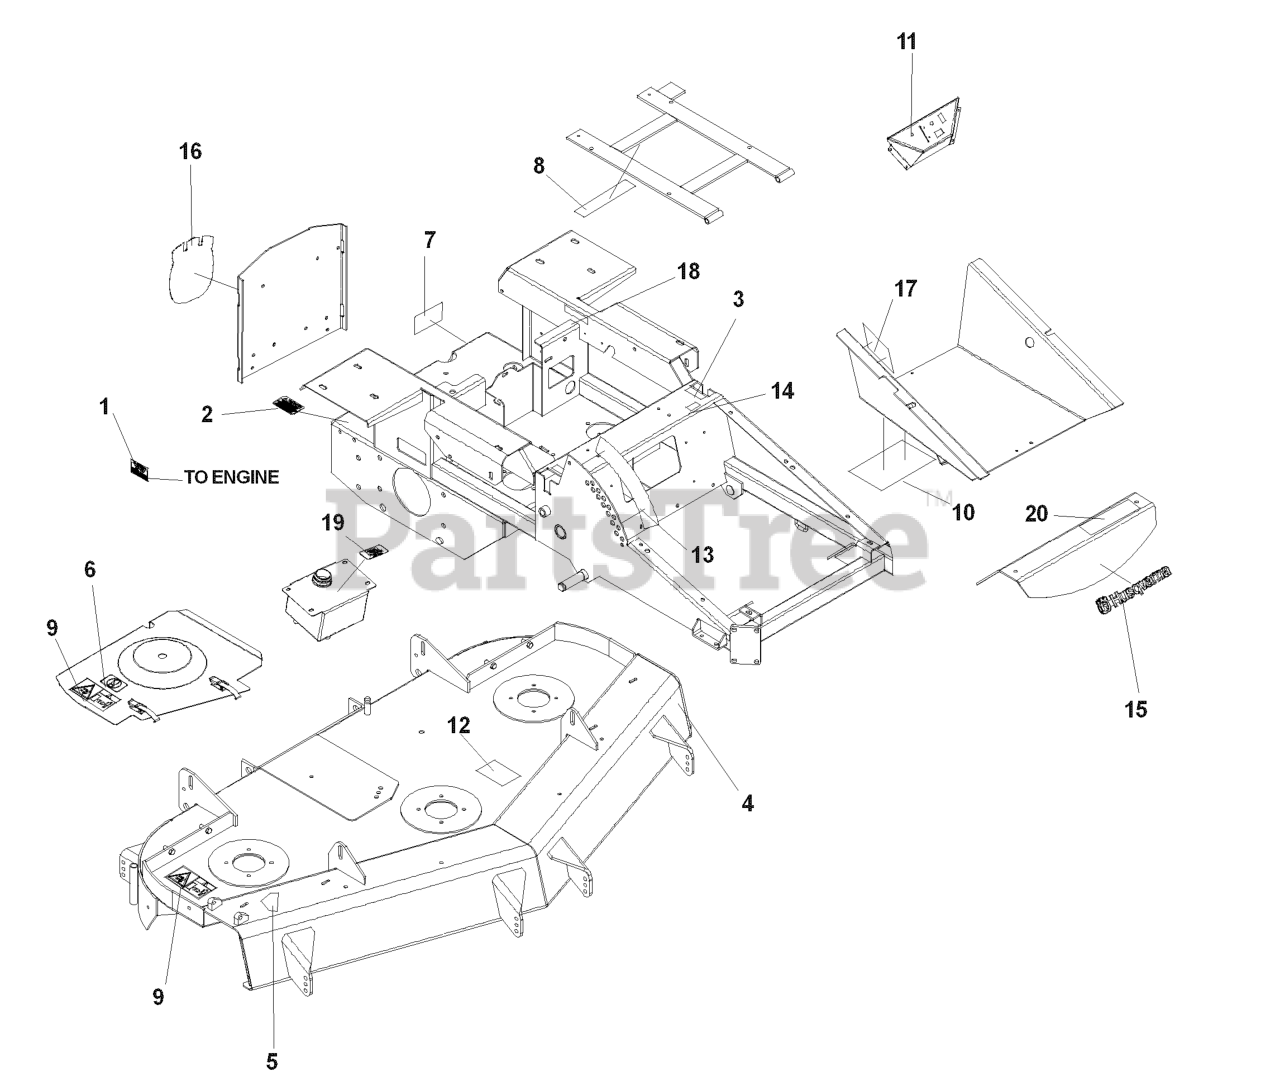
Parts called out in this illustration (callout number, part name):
1	DECAL, EXHAUST
2	DECAL, PROP. 65
3	DECAL, MOTION CONTROL
4	DECAL, NASCAR
5	DECAL, CPSC
6	DECAL, NO STEP
7	DECAL, BELT DRIVE
8	EURO DECAL-BATTERY WARNIN6
9	DECAL, EURO SEVERING
10	SERVICE DECAL
11	DECAL, CONSOLE
12	DECAL, BELT ROUTING
13	DECAL, HEIGHT ADJ
14	DECAL, F.S.T.
15	DECAL, HUSQ 12" BLUE
16	DECAL, CROWN H 5-1/4 SILVER
17	DECAL, WARNING
18	DECAL, RELAYS
19	DECAL, OIL TANK
20	DECAL, IZ4217
